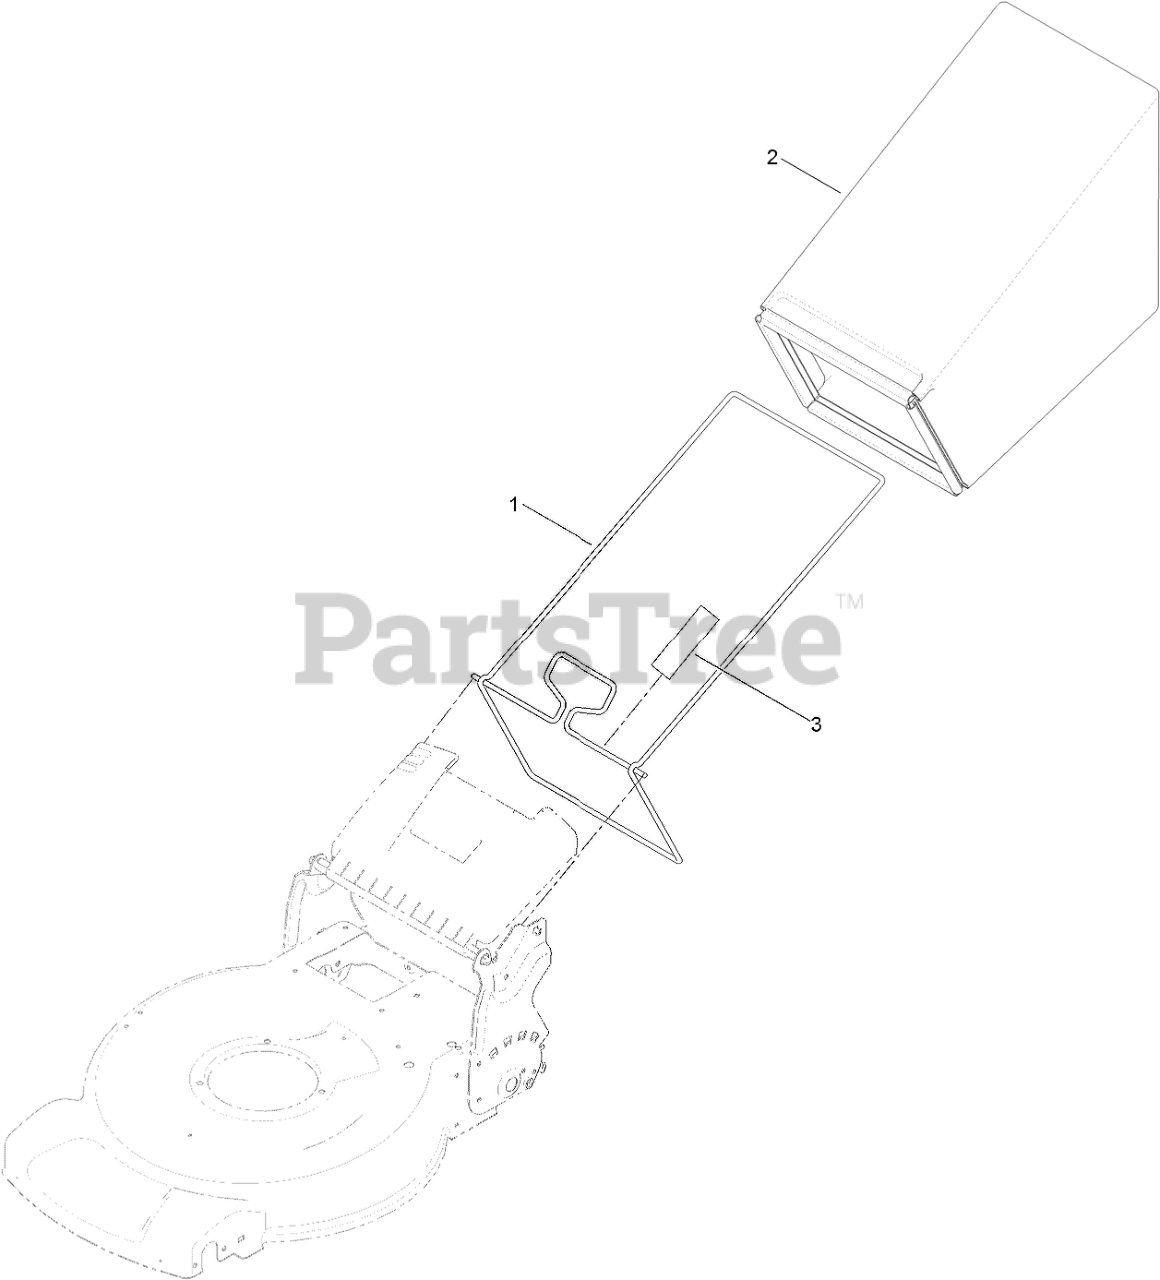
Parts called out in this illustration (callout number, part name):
1	BAG FRAME ASM
2	GRASS BAG ASM
3	Decal-Warning
